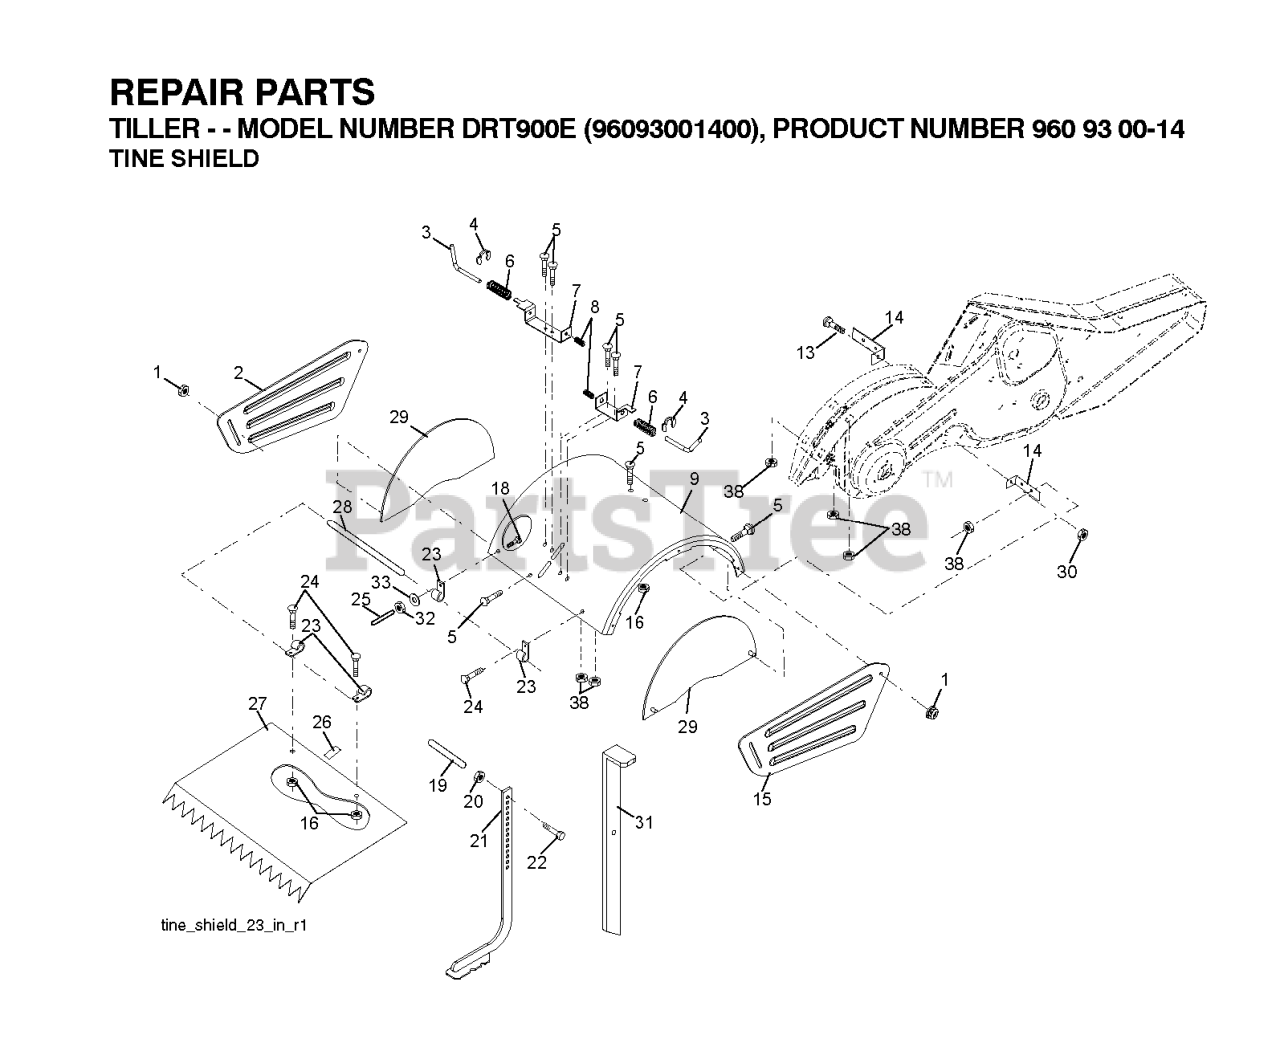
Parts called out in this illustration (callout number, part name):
1	NUT LOCK HEX FLANGE 5/16-18
2	SHIELD.PNT.SIDE.OUTER.LH.ORANG
3	STAKE PIN TI
4	RING, KLIP
5	BOLT, RDHD SQNK 5/16-18 X 3/4
7	BRACKET.LATCH.STAKE.3.20.BLACK
8	SPRING CRT
9	SHIELD.TINE.DRT17.TILLER.ORANG
13	BOLT.CARRIAGE.5/16-18
14	BRACKET.TINE.SHIELD.TILLER
15	SHIELD.SIDE OUTER.RH.ORANGE
16	NUT T
20	NUT.HEX.3/8-16UNC
21	STAKE.DEPTH.16.CRT.BLACK
22	BOLT.375-16
26	PAD IDLER TI
27	SHIELD.LEVELING.17".ORANGE
28	PIN.HINGE.TILLER
29	SHIELD.TINE.SIDE.ORANGE.TILLER
30	LOCKNUT-FLANGE 5/16-18
31	STAKE, DRAG
32	NUT
33	LOCKWASHER
38	NUT
